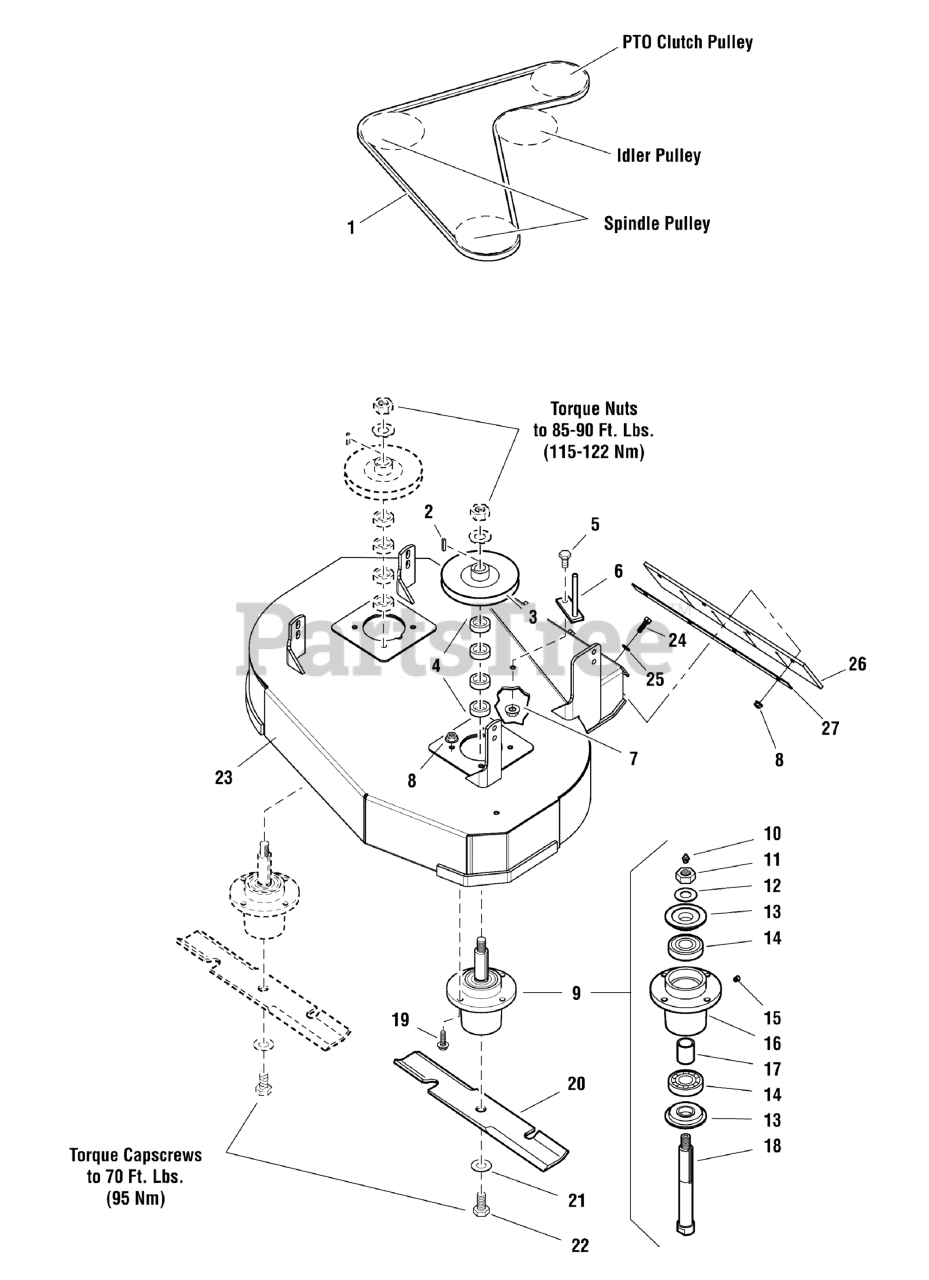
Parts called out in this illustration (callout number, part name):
1	BELT
2	KEY, 1/4 SQ. X 1
3	SPINDLE PULLEY
4	SPACER, 1.02 X 1.56 X .50
5	BOLT, 3/8-16 X 1" GD5 CZ
7	NUT, 1/4-20 HEX SERR. FLANGE
8	NUT, 5/16-18 Hex Nylock Flange
9	SPINDLE ASSM, ALUMINUM, LONG SHAFT
10	GREASE FITTING
11	NUT, 3/4-16 Hex
12	WASHER, 3/4" Belleville
13	TRASH SHIELD
14	BEARING
15	RELIEF VALVE
16	SPINDLE HOUSING
17	SPACER, 1.00 X 1.25 X 1.75
18	SPINDLE SHAFT
19	BOLT, Flange Head, 5/16-18 x 1-1/4
20	MOWER BLADE, 16-1/4"
21	WASHER, BLADE BOLT, 9/16" F436, CZ
22	BOLT, 5/8-11 x 1-3/4
23	DECK SHELL W/ DECALS (5405152B)
24	BOLT, 5/16-18 X 1 GD5 YZ
25	WASHER, 5/16" SAE
26	FLAP, RUBBER, 32RD
27	PLATE, RETAINING, 32RD - RED
